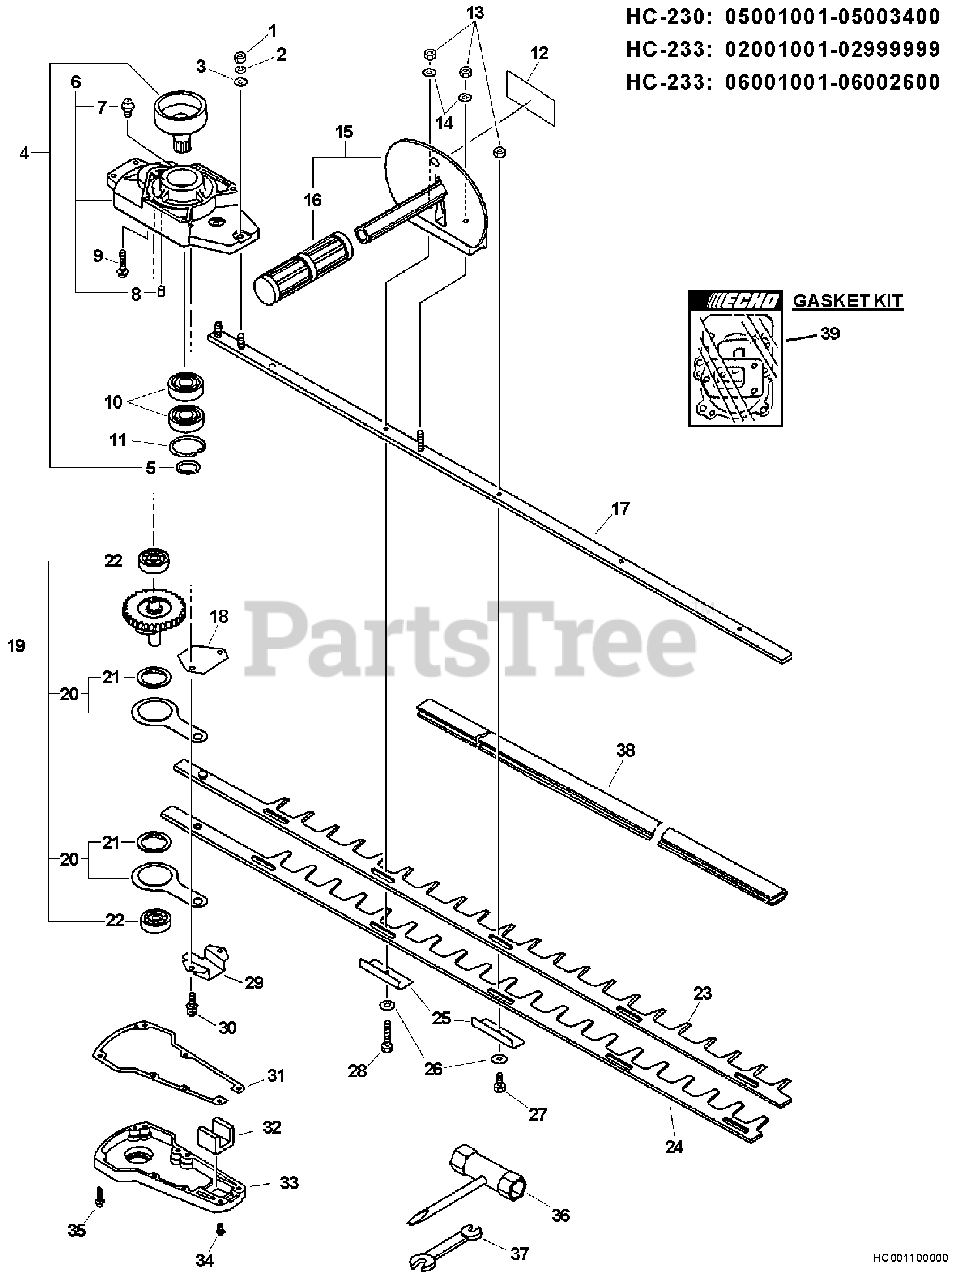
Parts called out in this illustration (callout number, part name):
1	NUT, HEX M6
2	WASHER, SPRING 6
3	WASHER 6.5×11.5×0.8
4	DRUM, CLUTCH
5	RING, RETAINING - 16
6	CASE, GEAR
7	FITTING, GREASE
8	PIN, LOCATING 4
9	BOLT 5×30
10	BEARING, BALL 6003
11	RING, SNAP 35
12	LABEL, CAUTION
14	WASHER 6.5×13×1
15	BRACKET ASSY
17	SUPPORT, BLADE
18	PLATE, GUIDE
19	GEAR ASSY
20	CONROD ASSY
21	BEARING, NEEDLE 30
22	BEARING, BALL 6200
23	BLADE - UPPER
24	BLADE - LOWER
25	INSULATOR
27	BOLT 6×22
28	BOLT 6×40
29	GUIDE, BLADE
30	BOLT 5×14
31	GASKET, GEAR CASE
33	LID, GEAR CASE
34	SCREW 4×14
35	SCREW 4×22
36	T-WRENCH 13×19×180
37	SPANNER 8×10
38	SCABBARD
39	GASKET KIT
